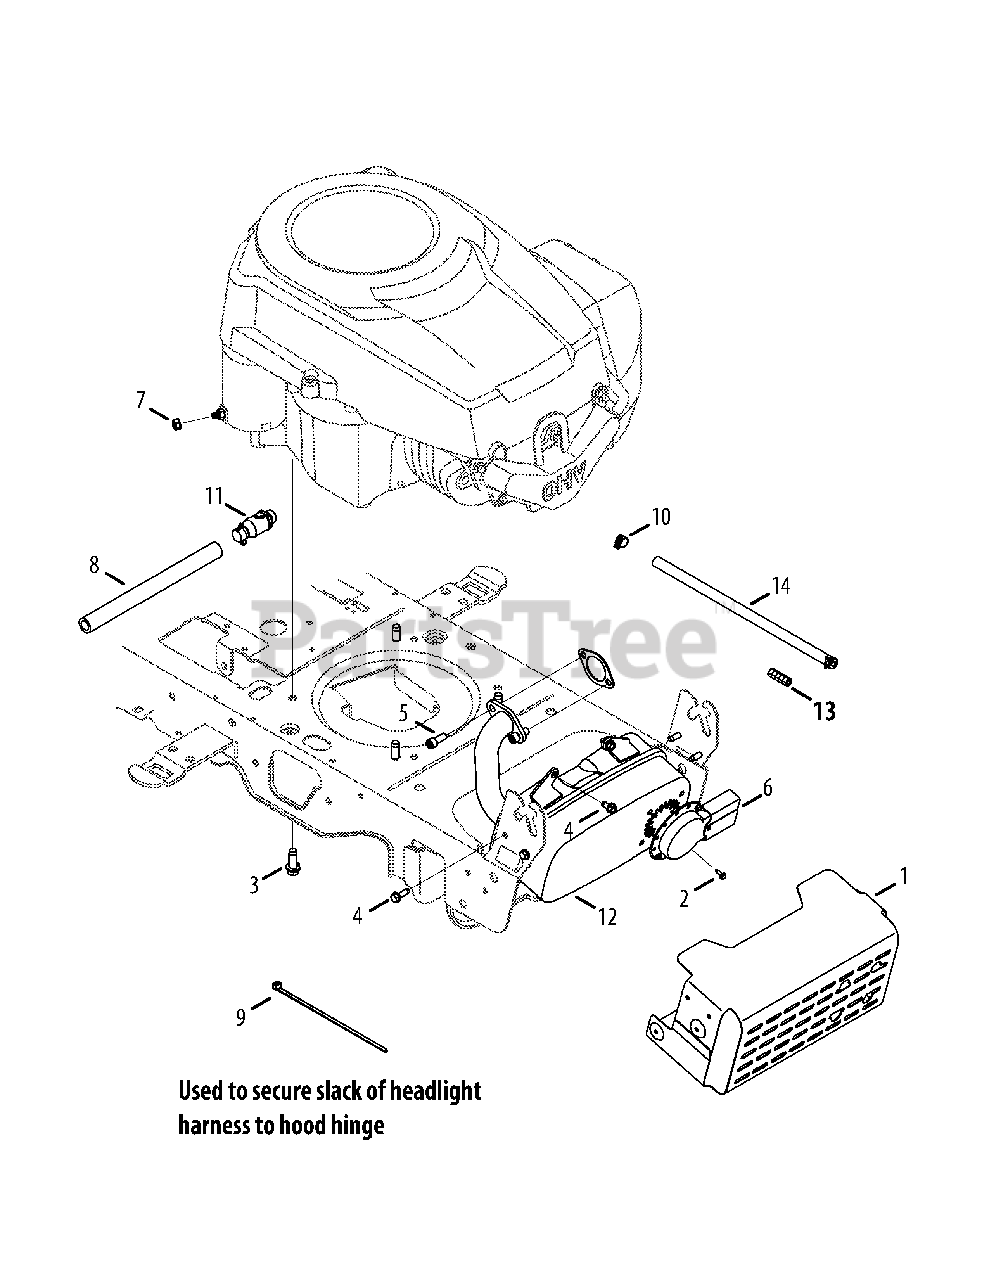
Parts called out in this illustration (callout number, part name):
1	Muffler Shield Assembly
2	Screw, Indented Washer, #8-18:0.500
3	Taptite Screw, 3/8-16:1.000
4	Taptite Screw, 1/4-20:0.500
5	Socket Head Screw, 5/16-18:.750
6	Long Muffler Deflector
7	Sems Nut, 1/4-20
8	Extension Hose, Oil Drain
9	Cable Tie, 3/16 x .05 x 7.4
10	Hose Clamp, .490 DIA.
11	Oil Drain
12	Muffler, Kohler
13	Hose, Vent
14	Fuel Hose
